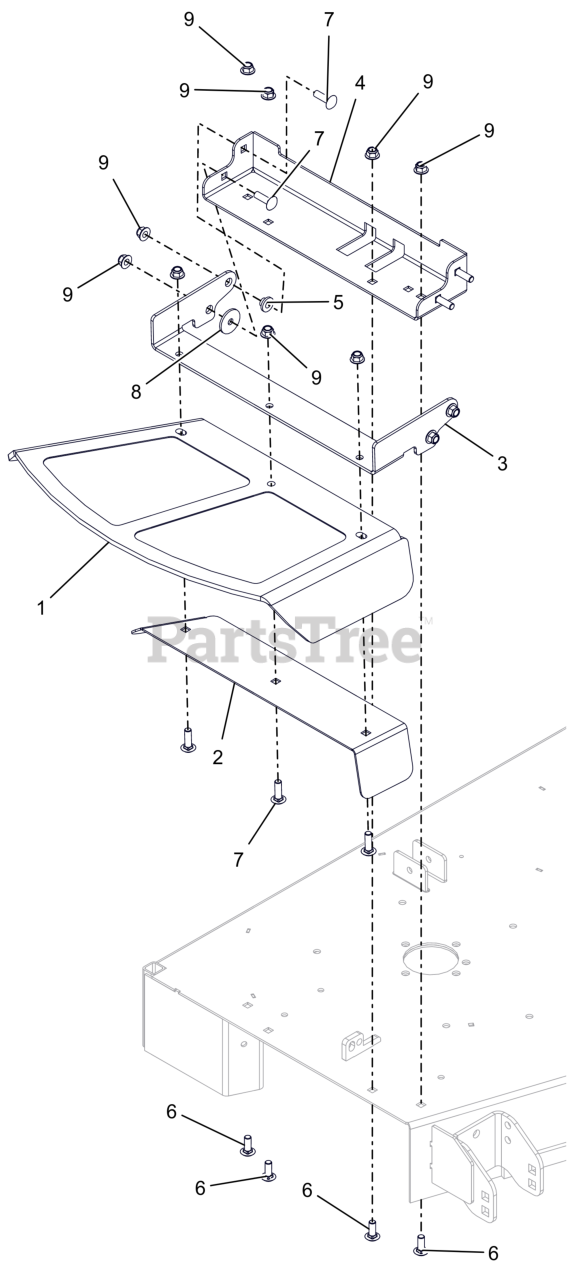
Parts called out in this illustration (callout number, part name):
1	CHUTE,48-60" FRMD RUBBER DISCH
2	PLT, DISCH. CHUTE CLMP-CE
3	BRKT, CE CHUTE MTG
4	WMT, DISCH. CHUTE-CE-W/SAFETY
5	BSHG-FLG .385X.500X.875X.406
6	BLT,RHSSN .38-16X1.00 G5 ZCC
7	BLT,RHSSN .38-16X1.25 G5 ZCC
8	WSHR, FLT .380X1.50X.125 ZCC
9	NUT,NYL-FLG .38-16 GF ZCC
